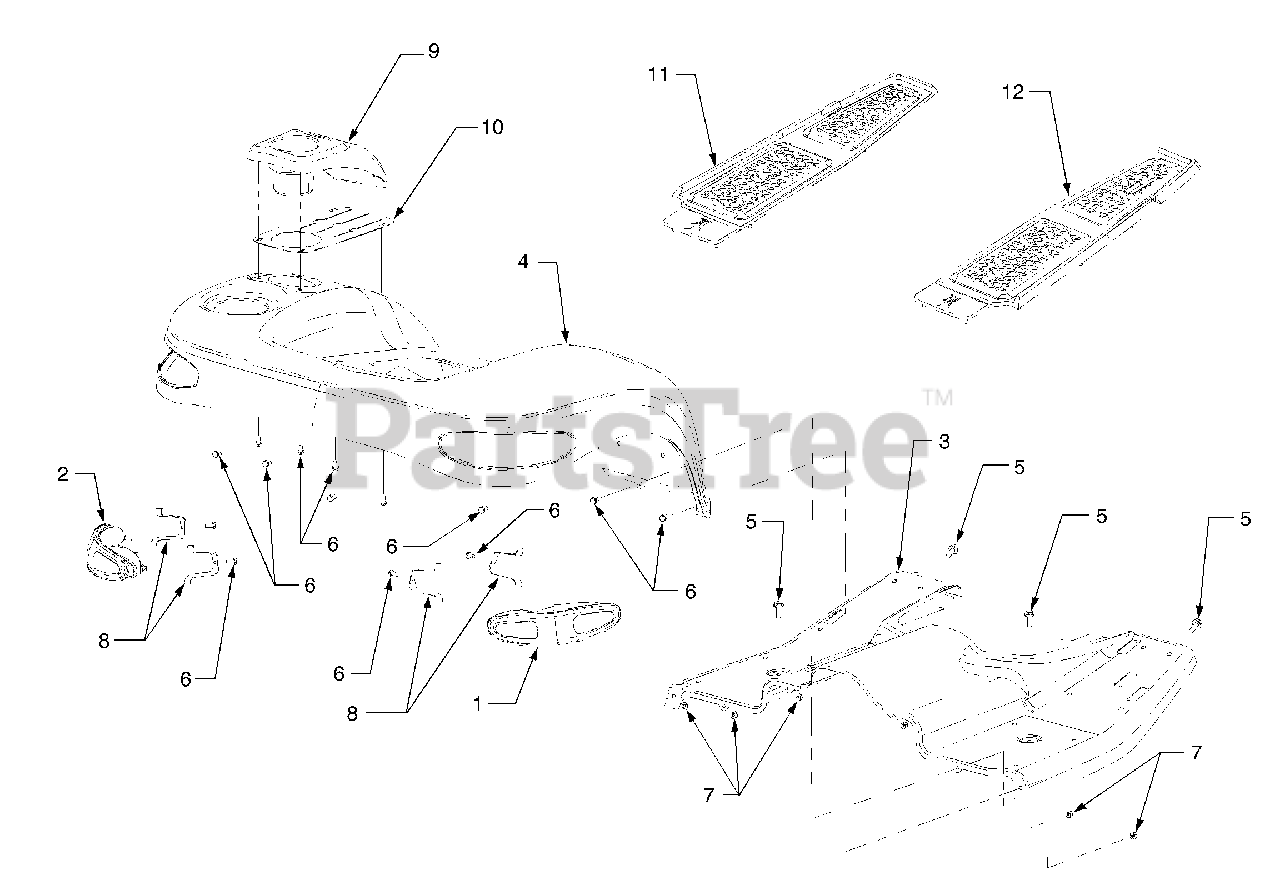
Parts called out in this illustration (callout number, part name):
1	Light Assembly, Rear RH
2	Light Assembly, Rear LH
3	Running Board
4	Fender
5	Screw, Hex Wash. Hd. Tapp 5/16-18 x 1.
6	Screw, Hex Cap, 1/4-20 x .5 GR5
7	Nut, Hex Lock, 1/4-20
8	Clip, Tail Light
9	Cover, Lift Lever
10	Flap, Lift Lever
11	Pad. Floor LH
12	Pad. Floor RH
